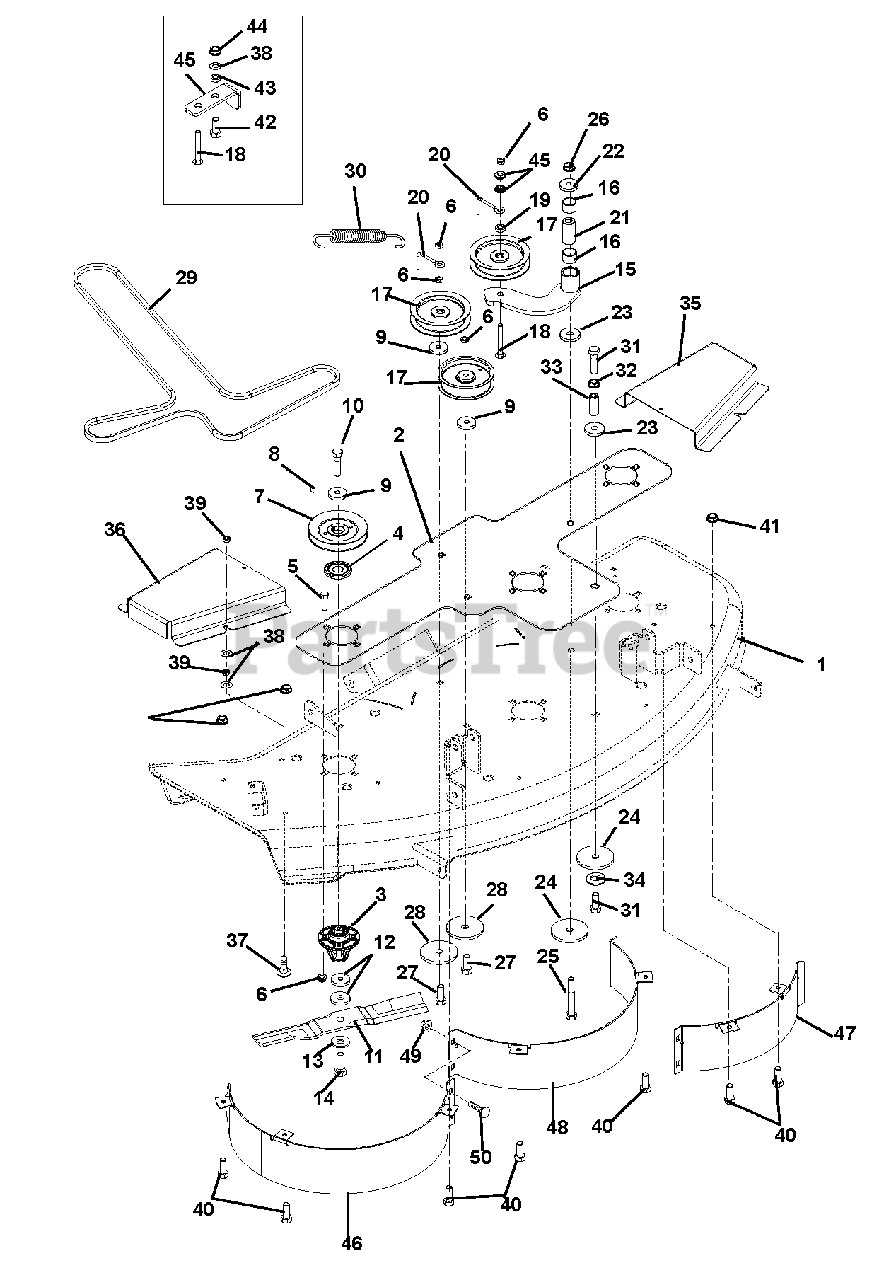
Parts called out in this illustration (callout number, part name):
1	WELDMENT, 40" STAMPED DECK
2	DOUBLER PLATE, ZOOM 40
3	SPINDLE ASSEMBLY
4	DUST CAP
5	@BLT-RDHDSQNK .38-16X1.25 G5YZ
6	@NUT-LK-NYL-FLG .38-16 YWZC
7	SHEAVE, 4.25 DIA A-SECTION
8	KEY, SQ .25 X .38 X .25
9	WSHR,FLT STL.406X1.50X.245YWZC
10	BLT-HEX .38-16X1.0 GR8 YZ EP30
11	BLADE, MULCH 13.88
12	WSHR-FLT .640X1.75X.250 YWZC
13	WSHR-BLVL .669X1.535X.138
14	BLT-HEX .62-18X1.75 GR8 YWZC
15	WMT, IDLER ARM
16	BRG, 1.00 X 1.12 X .75
17	IDLER, FLAT .38X4.00X1.06
18	@BLT-RDHDSQNK .38-16X2.50 G5YZ
19	BSHG-SLV .391X.688X.52 PM
20	BELT FINGER
21	BSHG, SPCR .502X.997X2.03 PM
22	WSHR-FL-STL.511X1.441X.125 YWZ
23	WSHR-FL-STL .515X1.625X.250 YZ
24	WASHER, FLAT .531X3.000X.25
25	@BLT-HEX .50-13X3.50 GR5 YWZC
26	@NUT-LK-TOP-FLG .50-13 YWZC
27	@BLT-HEX .38-16X2.75 GR5 YWZC
28	WSHR-FL-STL .469X2.00X.25 YWZC
29	V-BELT, HA-WRAPPED
30	EXTENSION SPRING
31	@BLT-HEX .50-13X1.25 GR5 YWZC
32	NUT-SPNLK-FLG .50-13 YWZC
33	NUT, COUPLING 1/2-13X1.75 YWZC
34	@WSHR-LK .50X.125 REG YWZC
35	BELT COVER, LEFT ZOOM 40
35	BELT COVER, LEFT
36	BELT COVER, RIGHT ZOOM 40
36	WMT, RH CE BELT COVER
37	@BLT-RHDSHSQNK.31-18X1.25 G5YZ
38	@WSHR-FL-STL.38X.875X.083 YWZC
39	@NUT-LK-NYL-FLG .31-18 YWZC
39	NUT- JAM .312-18 YWZC
40	@BLT-HEX .31-18X.75 GR5 YWZC
41	@NUT-SPNLK-FLG .312-18 YWZC
42	@BLT-HEX .38-16X1.00 GR5 YWZC
43	BSHG-SLV .377X.624X.235
44	@NUT-LK-TOP-FLG .38-16 YWZC
45	BELT FINGER
46	MULCH BAFFLE, RIGHT ZOOM 40"
47	MULCH BAFFLE, LEFT ZOOM 40"
48	MULCH BAFFLE, 40" ZOOM CENTER
49	@NUT-LK-TOP-FLG .31-18 YWZC
50	@BLT-RDHDSQNK .31-18X1.00 G5YZ
